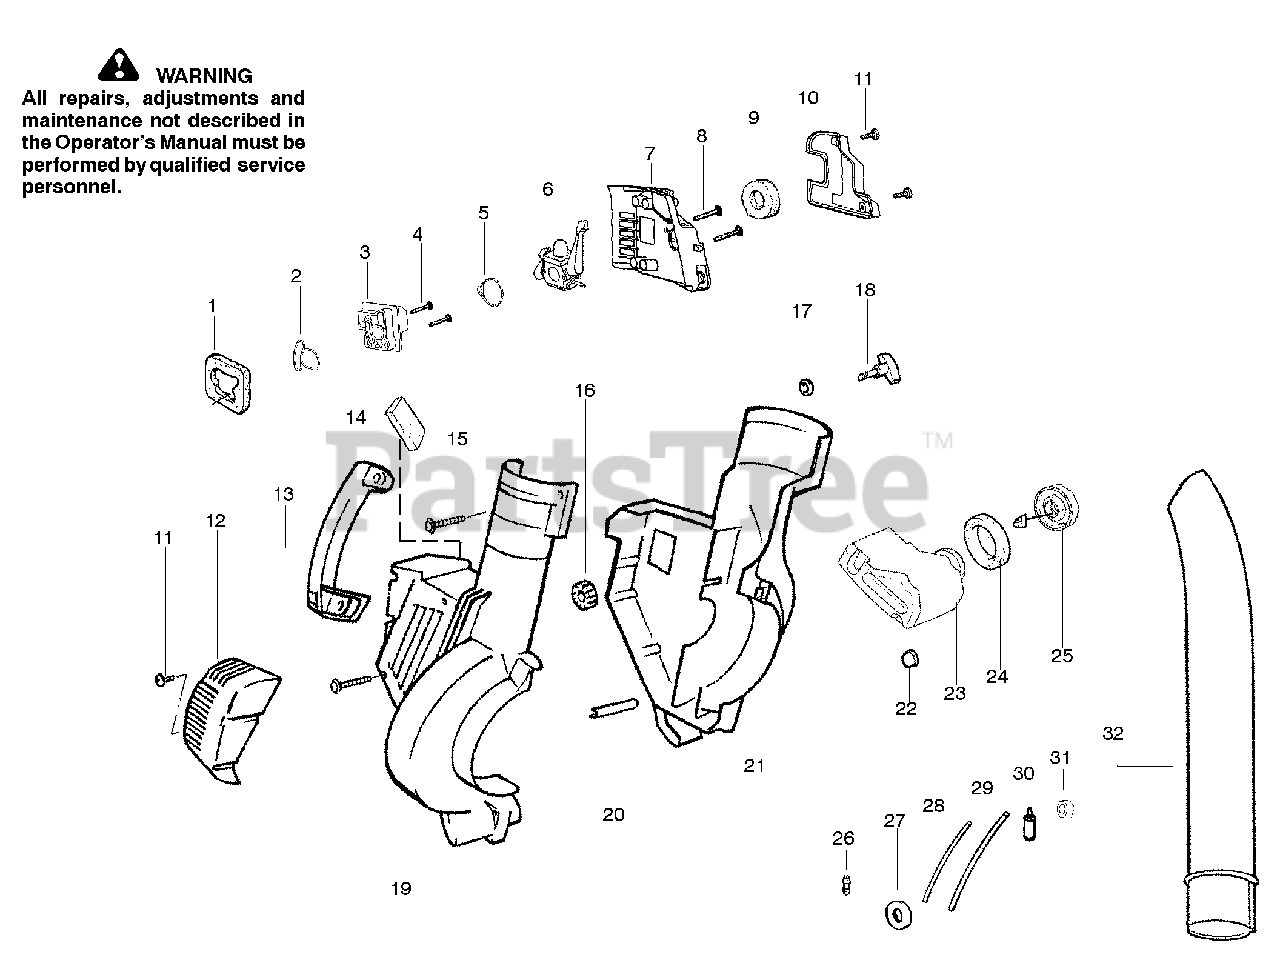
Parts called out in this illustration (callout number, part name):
1	Air Dam (kit)
2	Gasket-Adapter (kit)
3	Carburetor Adaptor
5	Gasket-Carburetor (kit)
6	Kit-Carb Ass'y. Zama-(C1Q-W11C)
6	Kit-Carb Ass'y. Walbro-(WT-606)
10	Cover-Air Filter
12	Guard-Muffler
14	Foam - 71.12mm (kit)
20	Guide-Starter Rope
22	Isolator-Crankcase
23	Assy-Fuel Tank
24	Gasket-Fuel Tank
25	Fuel Cap w/Retainer
26	Fitting-Fuel Line
27	Grommet-Shroud
28	Kit-Line Carb/Purge
29	Kit-Line Tank/Purge
30	Assy-Fuel Pick-up
31	Grommet-Fuel line (kit)
